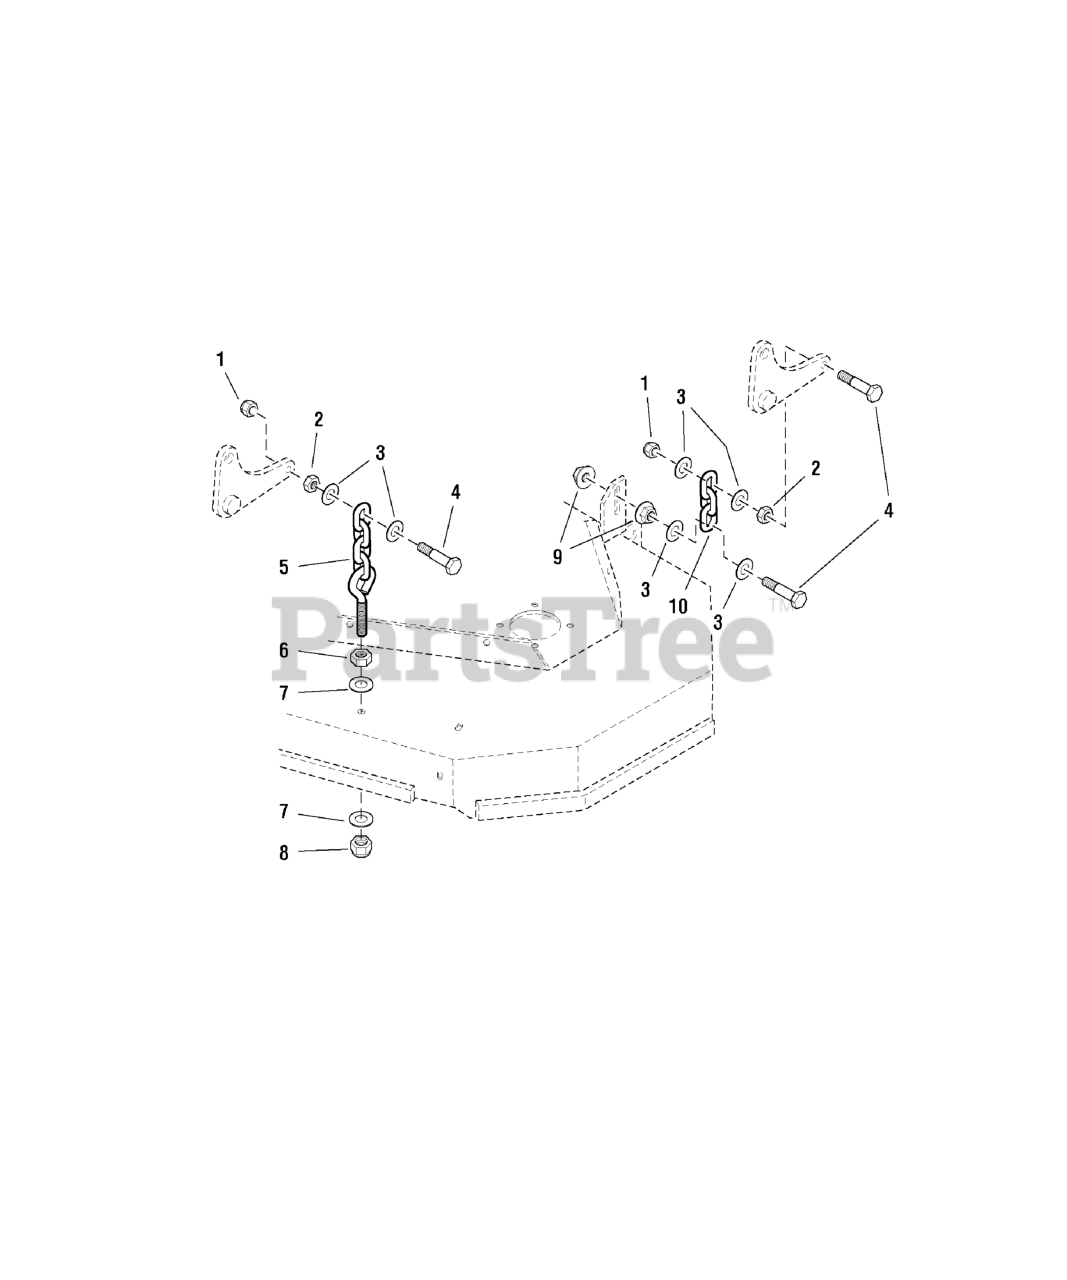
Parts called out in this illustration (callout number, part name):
1	NUT, 3/8-16 HEX NYLON LOCK
2	NUT, 3/8-16 HEX JAM
3	WASHER, 3/8 SAE
4	BOLT, 3/8-16 X 1-3/4" GD5 CZ
5	HANGER, FRONT DECK - 4 LINK, 5.5" EB
6	NUT, 1/2-13 Hex
7	WASHER, 1/2 SAE
8	NUT, 1/2-13 HEX NYLON LOCK
9	NUT, 3/8-16 Hex Serrated Flange
10	CHAIN, 3 LINKS
